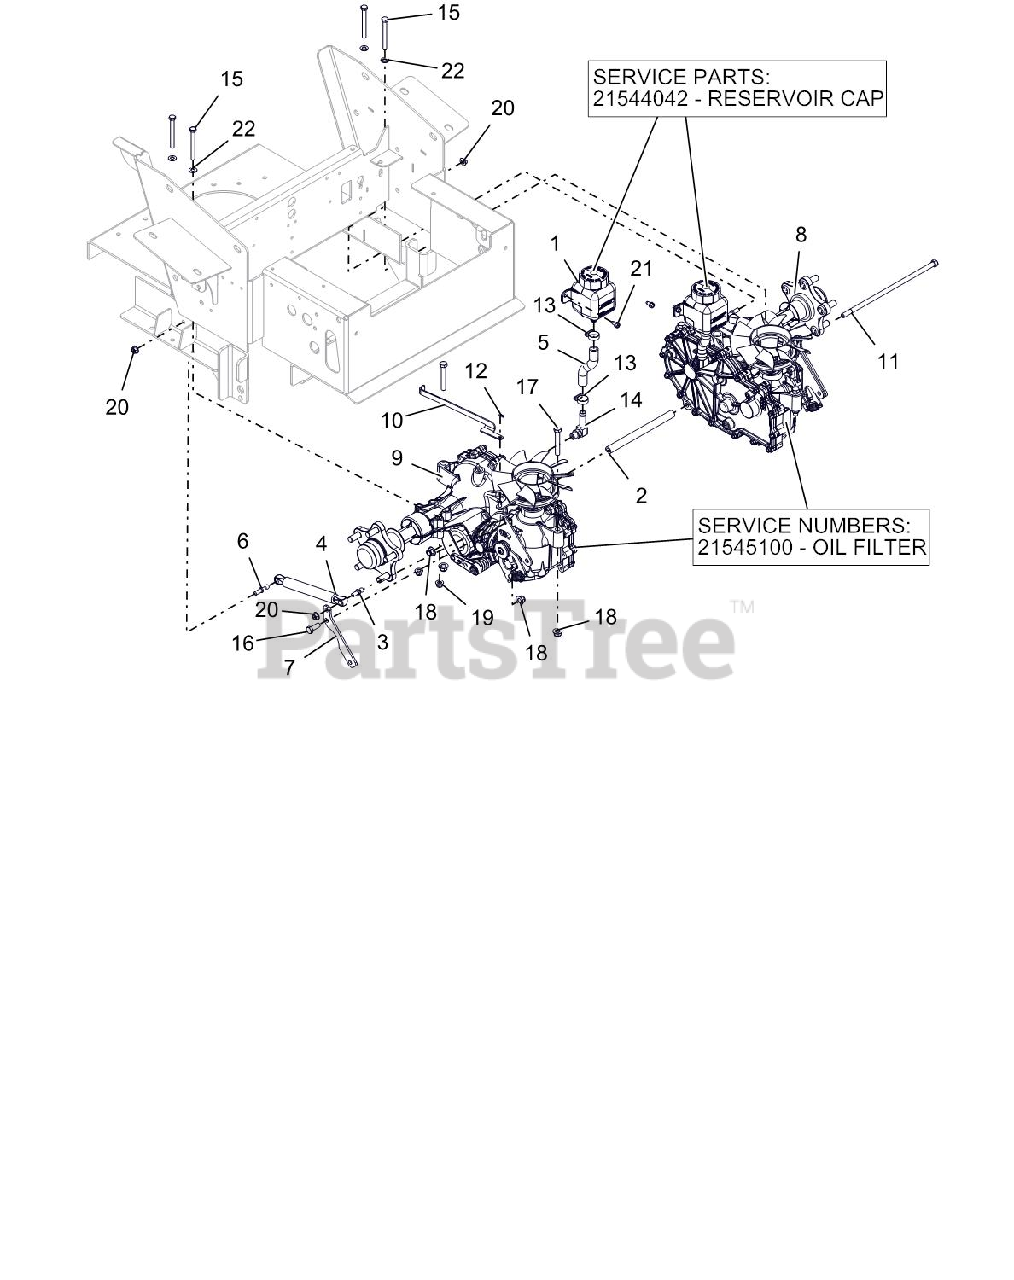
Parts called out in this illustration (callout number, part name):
1	TANK, EXPANSION
1	CAP, HYDRO RESERVOIR REPLAC.
2	SPCR,.406 ID X .630 OD X 7.724
3	STUD- BALL
4	DAMPER
5	HOSE, 100I HYDRO OVERFLOW
6	STUD-BALL-THREADED
7	TRANSMISSION DAMPER MTG PLT-BL
8	TRANSAXLE, ZT3200, LH
9	TRANSAXLE, ZT3200, RH
10	DUMP VALVE BRKT - BLACK
11	BLT HEX, .38-16X11.00 GR5 YWZC
12	PIN-HAIR INT .06X.18X.77
13	CLAMP,.88 DIA. HOSE
14	FITTING, HYD (90 DEG)
15	@BLT-HEX .31-18X3.00 GR5 YWZC
16	@BLT-HEX .38-16X1.00 GR5 YWZC
17	@BLT-HEX .38-16X2.50 GR5 YWZC
18	@NUT-LK-NYL-FLG .38-16 YWZC
19	@NUT-LK-NYL-FLG .31-18 YWZC
20	@NUT-LK-TOP-FLG .31-18 YWZC
21	SCR-TAP .25-20X.50 HWH TR YWZ
22	@WSHR-FL-STL.344X.688X.065YWZC
23	OIL FILTER, TRANSMISSION
